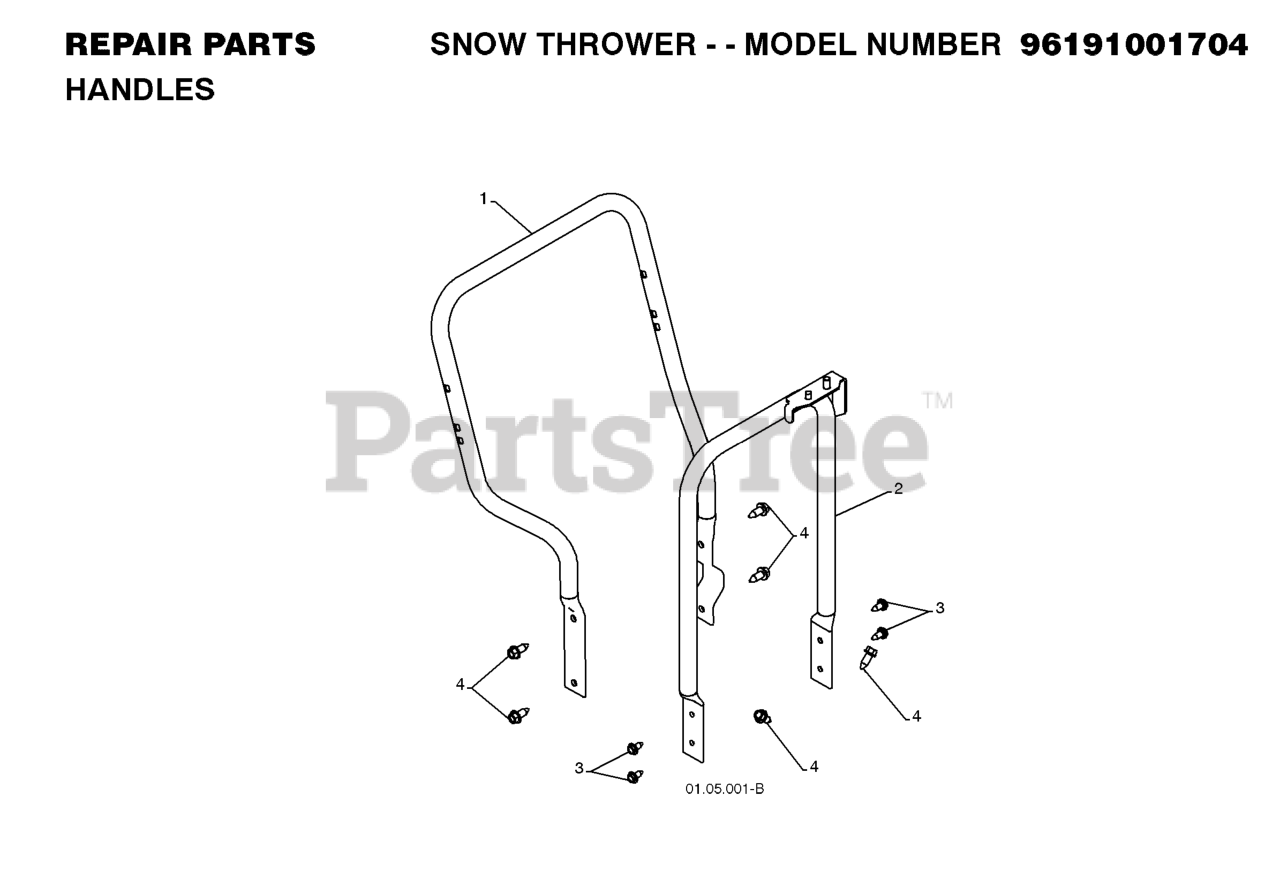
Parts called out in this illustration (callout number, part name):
2	RP PIVOT SUPPORT
3	SELF-TAPPING SCREW 5/16-18X3/4
4	SCREW 3/8-16X1
